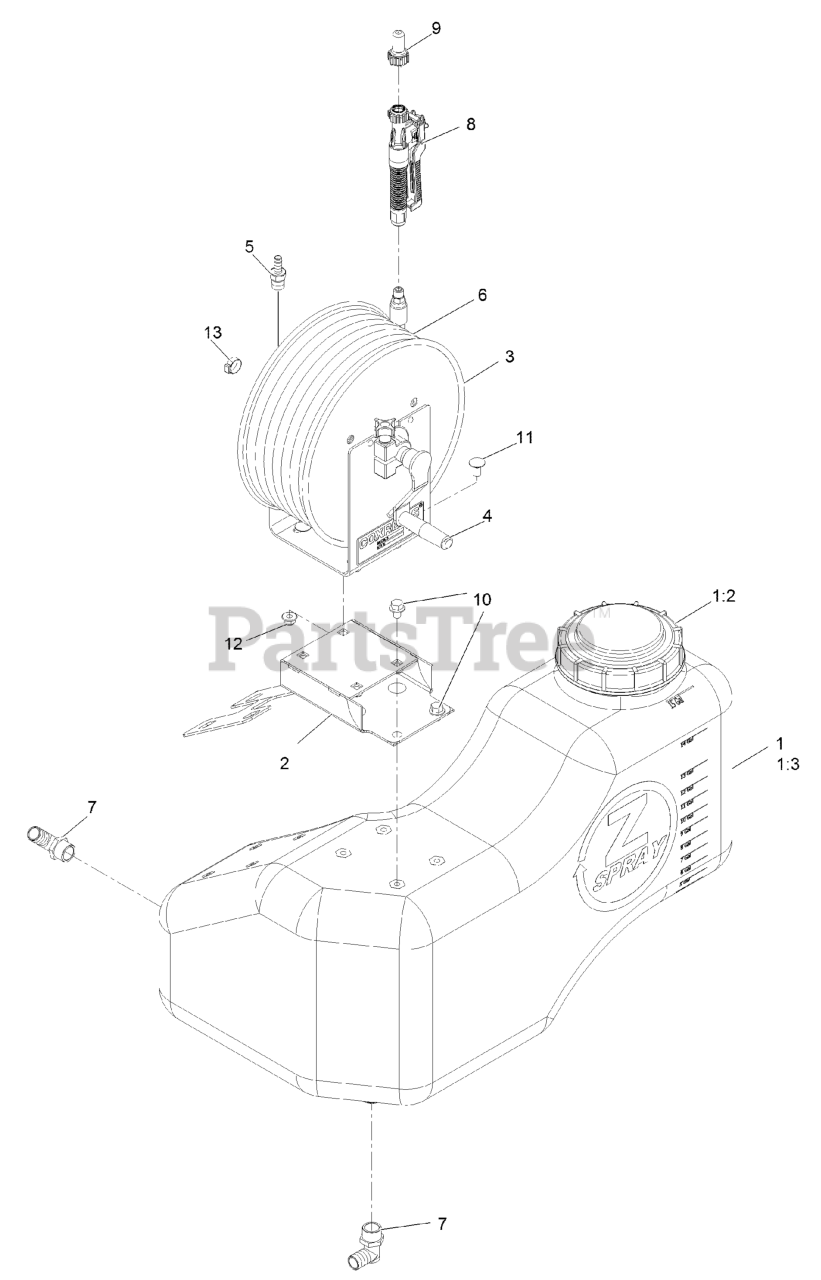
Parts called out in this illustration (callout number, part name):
1	ASM-TANK, LT
1:2	CAP-TANK, SPRAY
1:3	FITTING-BULKHEAD
2	MOUNT-REEL, HOSE
3	REEL-HOSE
4	Crank-Reel
5	FITTING,MALE
6	HOSE-SPRAY, 75'
7	FITTING-ELBOW, 90
8	GUN-SPRAY, SPOT
9	TIP-SPRAY, #12 SPOT
10	Screw-HHF
11	SCREW-CARRIAGE
12	Nut-Hex Flange
13	CLAMP-OETIKER, 167
